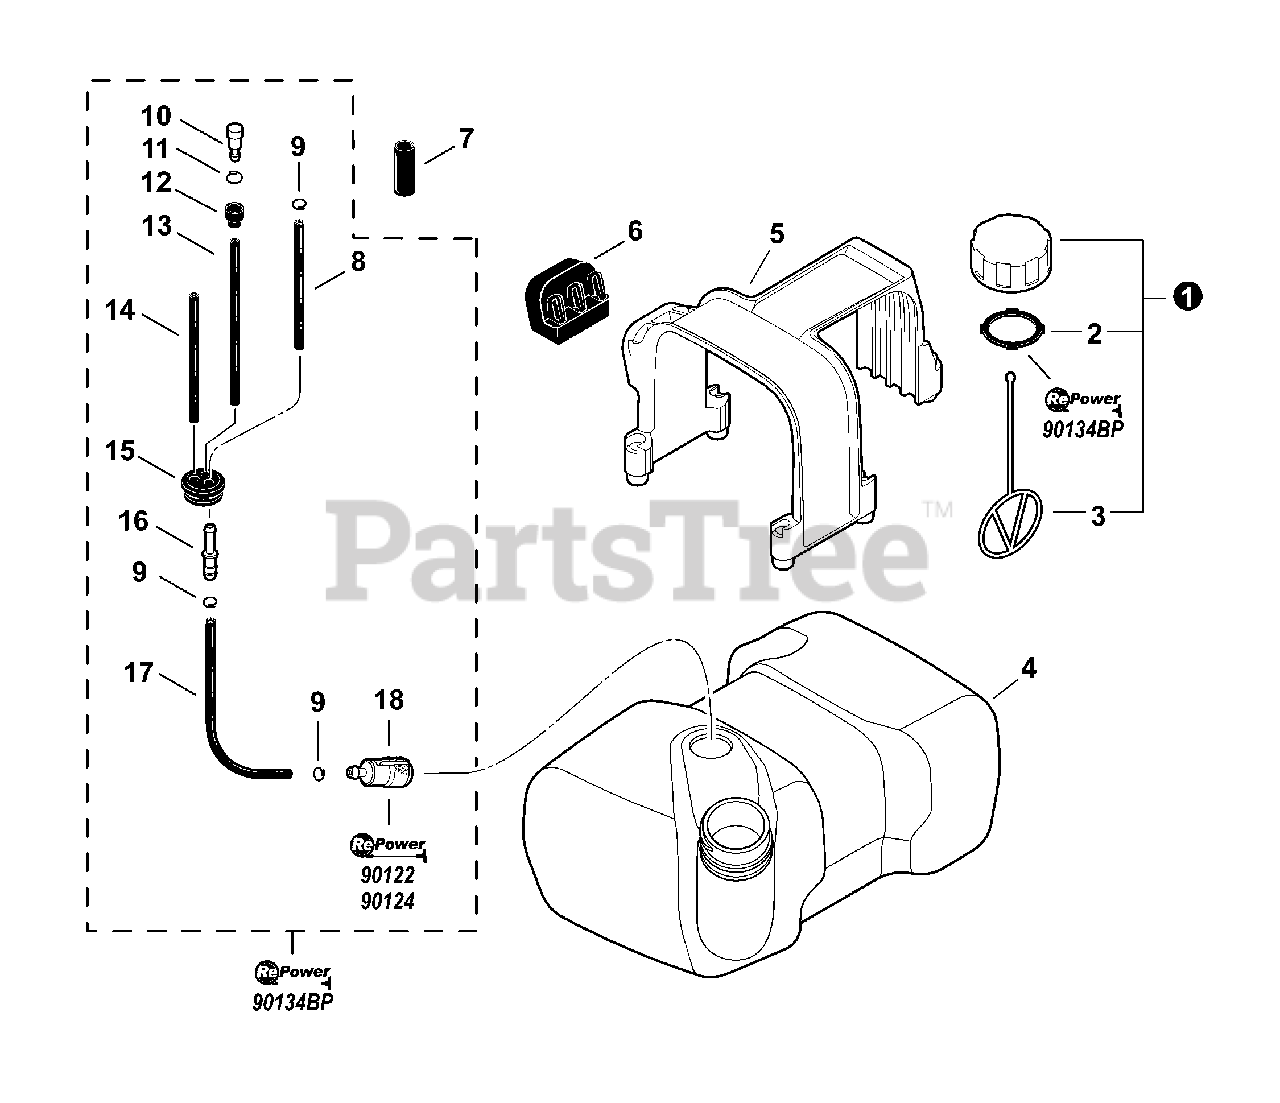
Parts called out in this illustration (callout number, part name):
1	CAP ASSY, FUEL
2	GASKET, FUEL CAP
3	CONNECTOR, CAP L= 100 MM
4	TANK, FUEL
5	RETAINER, FUEL TANK
6	CUSHION
7	TUBE, FUEL LINE 16×18×L40
8	PIPE, FUEL 3×5×135L BLACK
9	CLIP Ø6
10	VENT ASSY
11	CLIP Ø6.5 MM
12	HOLDER, VENT
13	PIPE, FUEL 3×6×130 BLACK
14	PIPE, FUEL 2.4×5×200 BLACK
15	GROMMET, FUEL
16	CONNECTOR, PIPE Ø5ר3.5
17	PIPE, FUEL 3×5×105L BLACK
18	FILTER, FUEL 125-528
